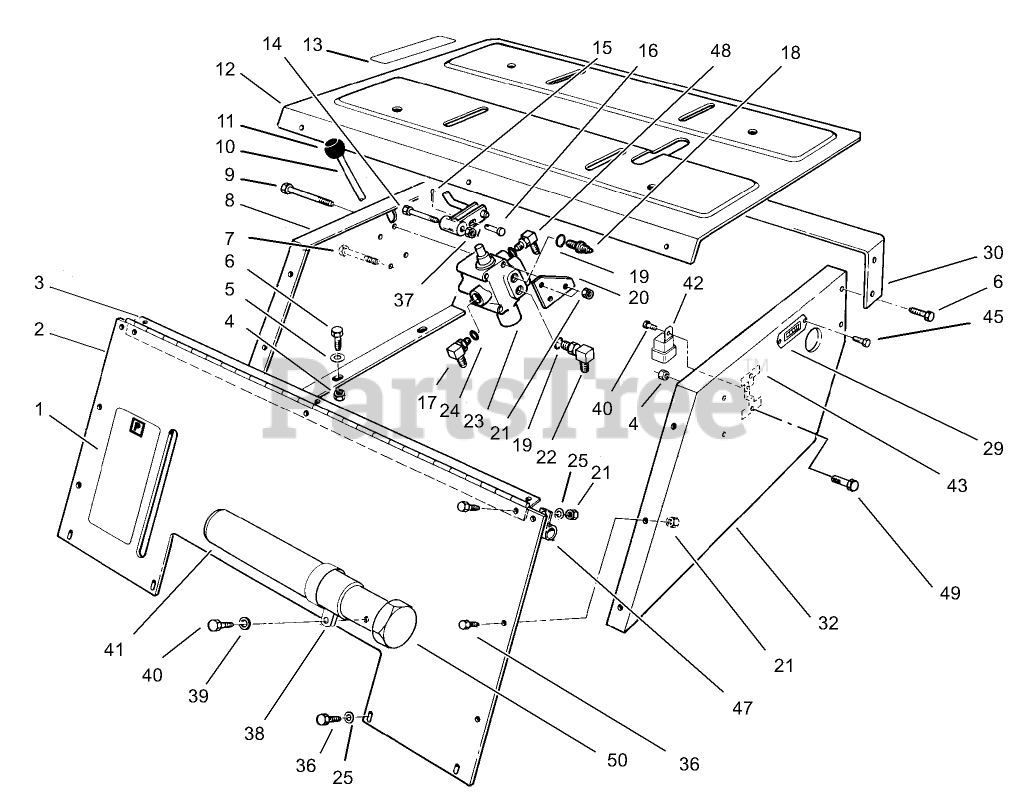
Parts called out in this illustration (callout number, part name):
1	PARK BRAKE DECAL
2	Support-Seat, Front
3	Hinge-Seat
4	NUT-LOCK, NI
5	WASHER-PLAIN
6	SCREW-HH
7	SCREW-HH
8	Support-Seat RH.
9	SCREW-HH
10	Lever-Valve
12	Plate-Seat
13	LIFT CONTROL DECAL
14	BOLT-WHEEL
15	PIN-COTTER
16	PIN-CLEVIS
17	FITTING-HYD, 90 DEG
18	FITTING-STRAIGHT
19	O-RING
20	LEVER BRACKET
21	NUT-LOCK, NI
22	FITTING-ELBOW, 90
23	VALVE ASM
24	O-RING
25	WASHER-FLAT
29	HOURMETER
30	Support-Hood
32	Support-Seat L.H.
36	SCREW-HH
37	NUT-LOCK, NI
38	CLAMP-R
39	WASHER-FLAT
40	SCREW-HWH
41	TUBE-MANUAL
42	RELAY
43	Bracket
45	SCREW-HWH
48	FITTING-ELBOW-90 DEG
49	SCREW-HH
50	TUBE-MANUAL
